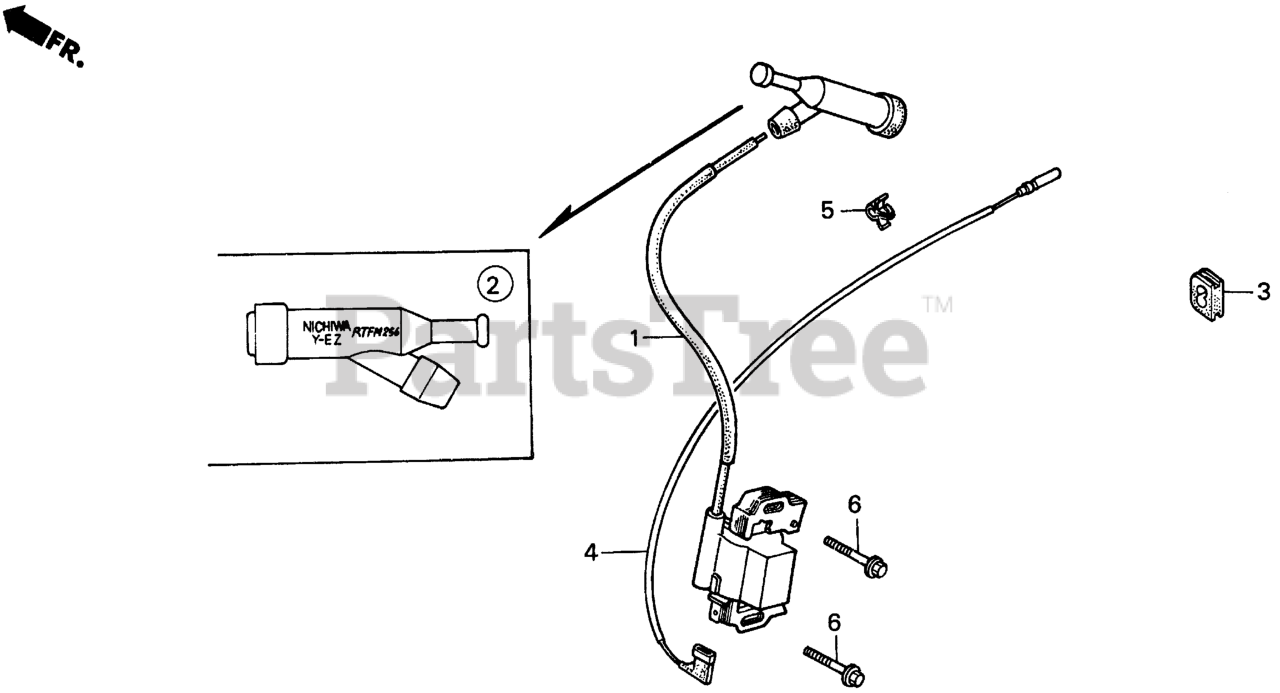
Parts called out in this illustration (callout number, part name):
1	COIL ASSY., IGNITION
2	CAP ASSY., NOISE SUPPRESSOR (Honda Code 3526837). (NICHIWA Y-EZ RTFM256)
3	GROMMET, WIRE
4	WIRE, STOP SWITCH (Honda Code 2026672). (NOT AVAILABLE)
5	HOLDER, STOP SWITCH WIRE Use up to Engine SN 2056819.
6	BOLT, FLANGE (6X28) (CT200) Use up to Engine SN 1530314.
